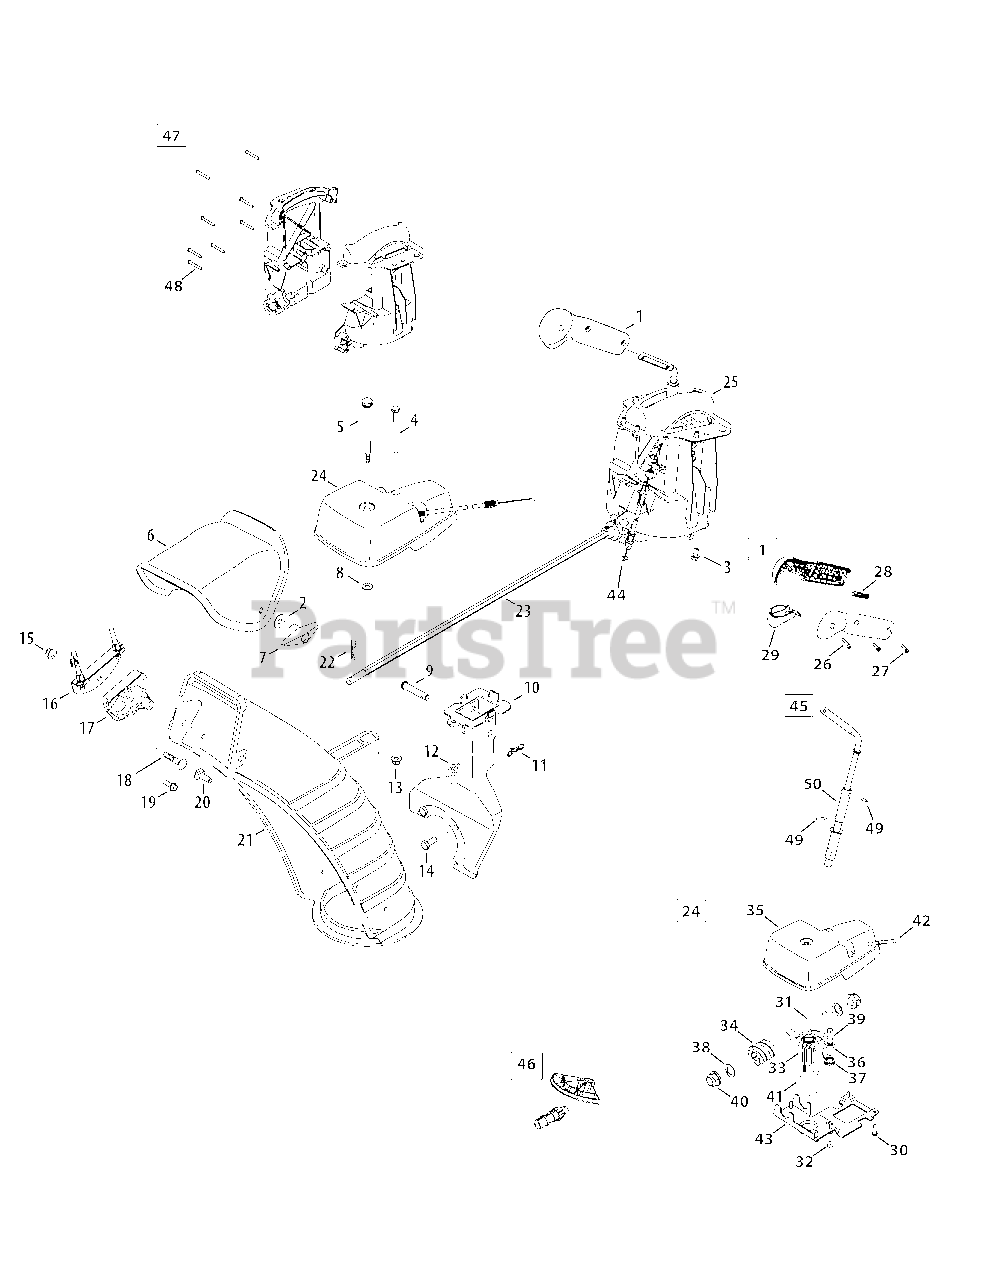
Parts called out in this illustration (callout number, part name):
1	Trigger Handle Housing Assembly Kit
2	Washer, Flat, .349 x .879
3	Hex Washer Screw, 1/4-15 x .50
4	Hex Head Screw, 1/4-20 x 3.00
5	Screw, Shoulder, .312 x 3.5 x 1/4-20
6	Upper Chute
7	Wing Knob
8	Washer, Flat, .25 x .630
9	Clevis Pin, 3/8 x 1.87
10	Chute Support Bracket
11	Bow-Tie Cotter Pin
12	Wing Nut, 1/4-20
13	Flange Lock Nut, 1/4-20
14	Hex Lock Screw, 5/16-24 x .750
15	Flange Lock Nut, 5/16-18
17	Chute Tilt Cable Guide
18	Carriage Bolt, 5/16-18 x 1.50
19	Hex Washer Screw, 1/4-15 x .750
20	Carriage Bolt, 5/16-18 x 1.00
21	Lower Chute, 5.0
22	Internal Cotter Pin
23	Chute Rod, 3/8 Hex
24	Gearbox Assembly, Chute Rotation
25	4-Way Chute Control Assembly
26	Screw, #8 x 1.00
27	Screw, 8-32 x .750
28	Joystick Plug
29	Joystick Trigger
30	Screw, 12-16 x .75
32	Hexlock Nut, 1/4-28
33	Gear, 14 T
34	Worm
35	Gear Cover
36	Pawl Lock
37	Torsion Spring, .721 ID x .474
38	Washer, Flat, .625 x 1.0 x .067
39	Screw, Shoulder, .340 x .950 x 1/4-28
40	Hex Bearing
41	Flange Bearing
43	Gear Bracket
44	4-Way Cable
44	4-Way Cable w/Clip
45	Shift Assembly
46	Gear Set Assembly Kit
47	Chute Control Housing Kit, 4-Way
48	Screw, #8-18 x 1.250
50	Block, Assembly Joint
